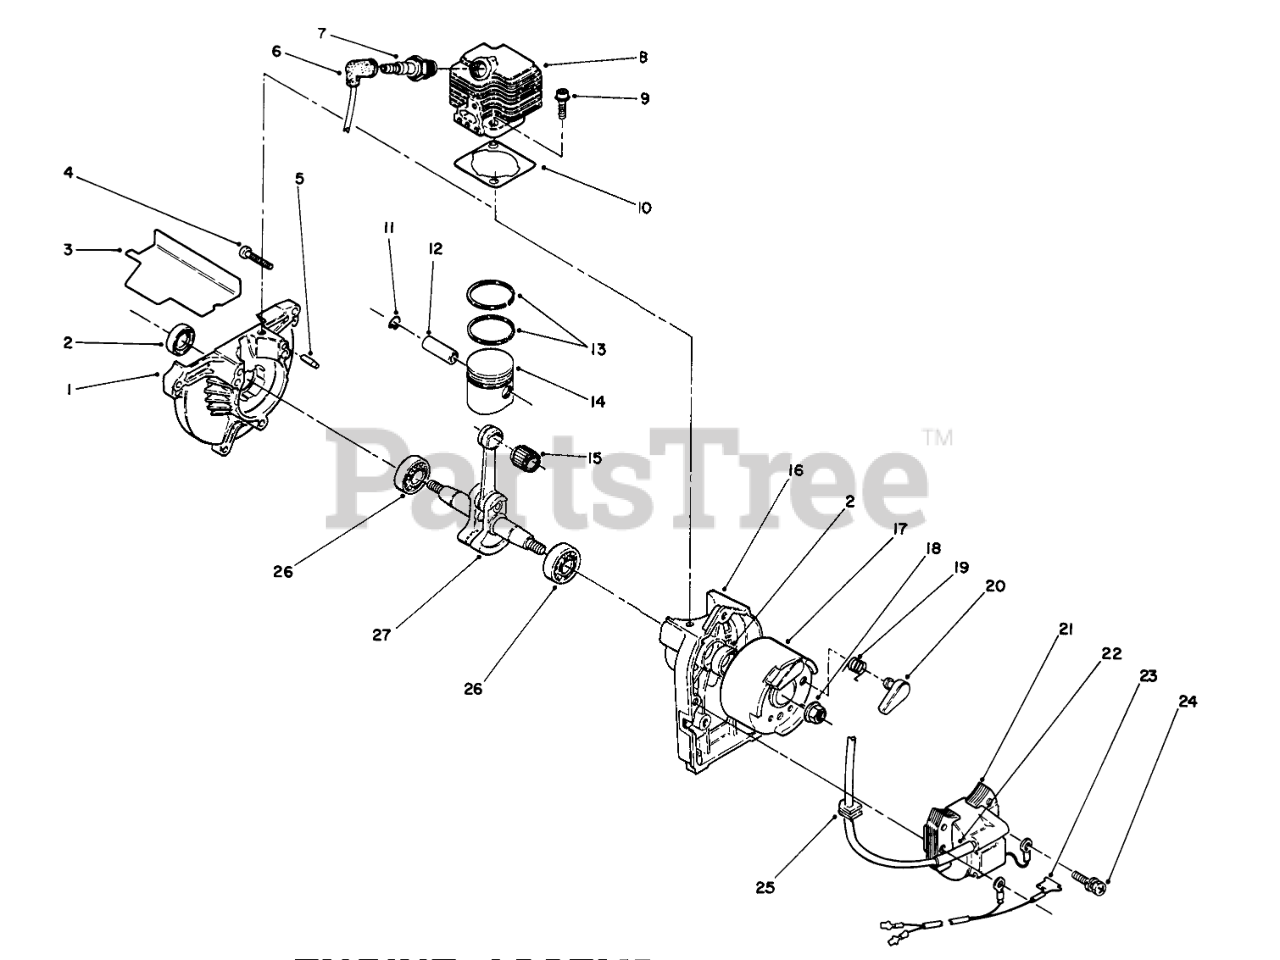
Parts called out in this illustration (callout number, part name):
1	DRIVE CASE
2	OIL SEAL
3	BAFFLE GASKET
4	Screw
6	PLUG BOOT
7	SPARK PLUG (NGK)
8	CYLINDER
9	FLANGE BOLT
10	CYL GASKET
11	PISTON PIN CLIP
12	Pin-Piston
13	TOP RING
14	Piston Assembly (Incl. Ref. #11 & 12)
15	NEEDLE BEARING
16	STARTER CASE
17	Flywheel Assembly (Incl. Ref. #19 & 20)
19	RETURN SPRING
20	RATCHET
21	IGNITION COIL
23	Wire Assembly
24	BOLT AND WASHER
25	GROMMET
26	BEARING
27	CRANKSHAFT ASSEMBLY
